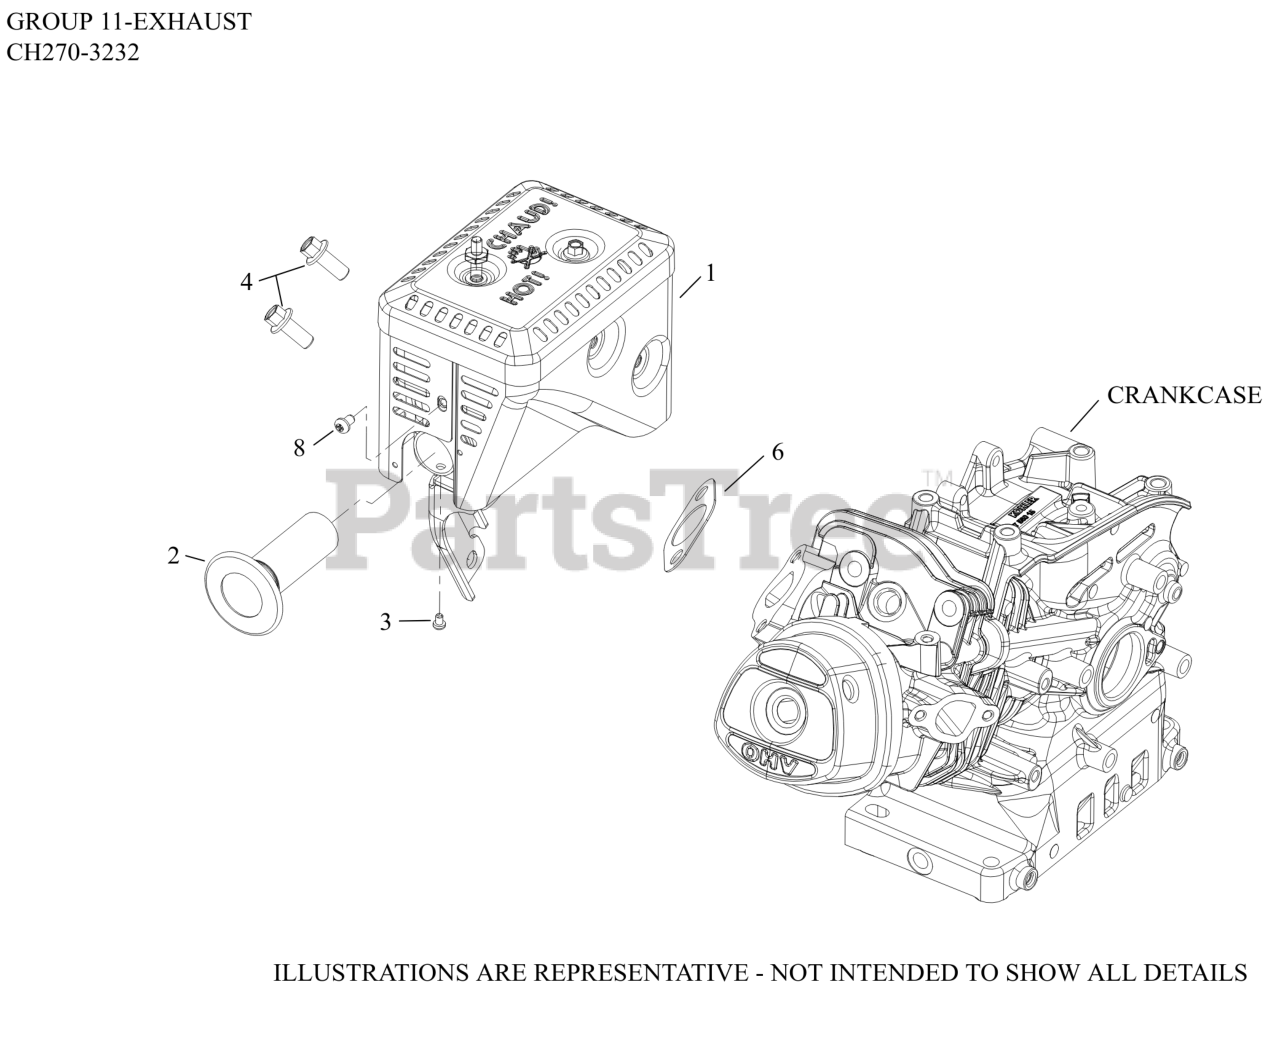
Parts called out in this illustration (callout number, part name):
1	KIT, MUFFLER
2	ARRESTOR ASSEMBLY, SPARK
3	SCREW, SPARK ARRESTOR
4	SCREW, M8 X 20
6	GASKET, MUFFLER
8	SCREW, M5 X 8
